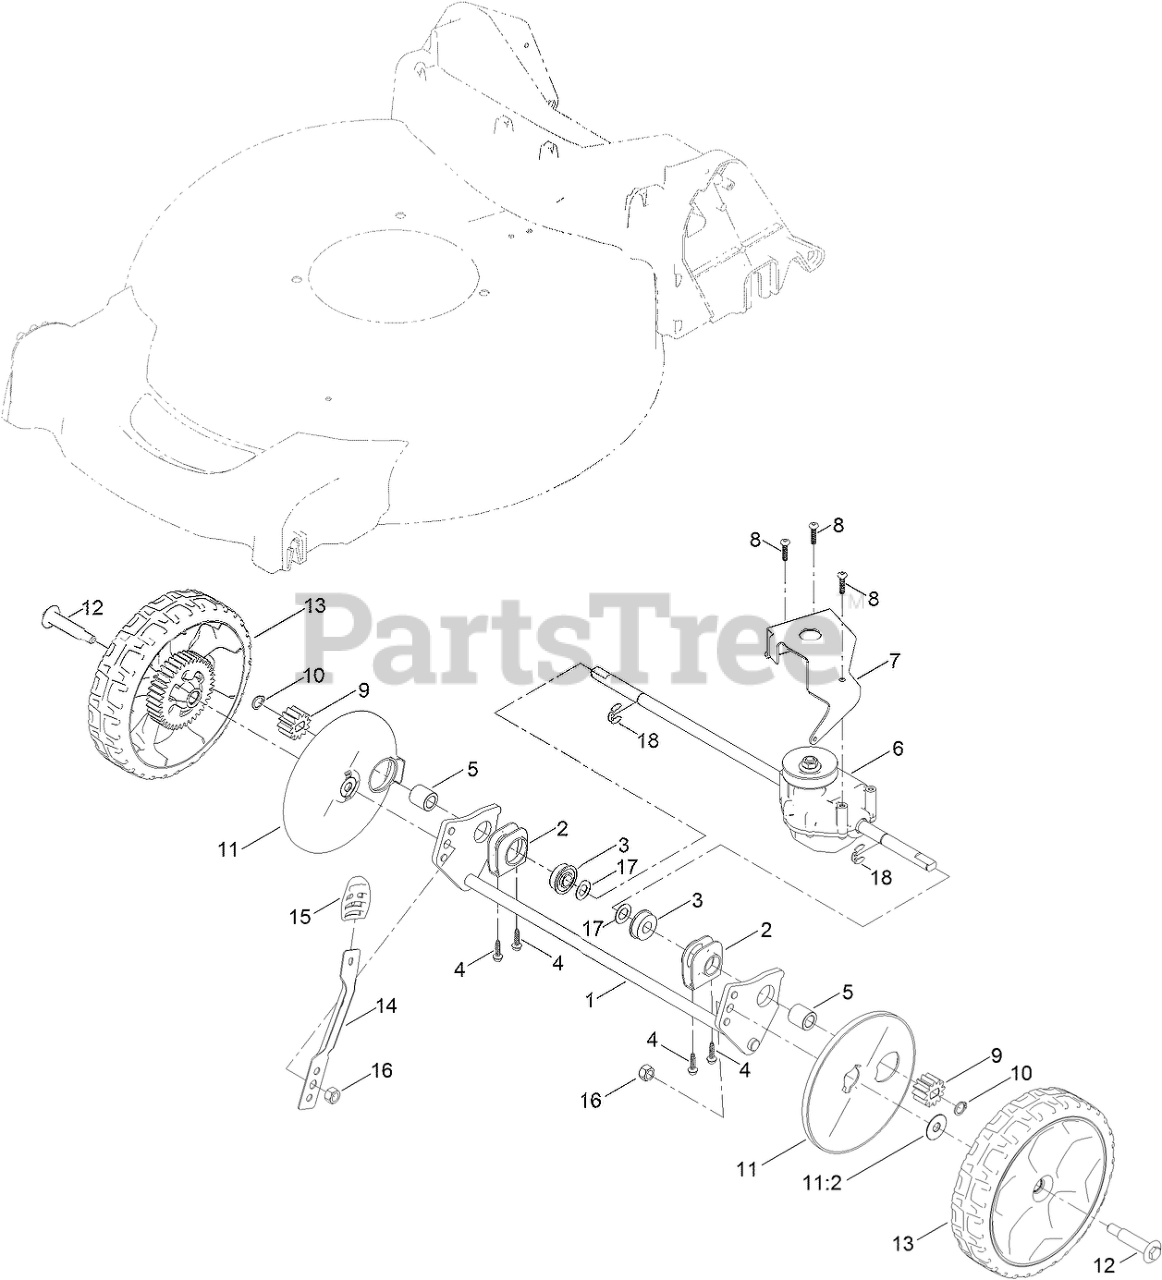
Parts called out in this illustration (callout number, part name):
1	AXLE-REAR
2	RETAINER-BEARING
3	BEARING-BALL
4	SCREW-PLASTIC, HWH
5	BUSHING-SLEEVE
6	TRANSMISSION
7	BRACKET-TRANSMISSION
8	SCREW-PLASTITE
9	GEAR-PINION
10	RING-RETAINING
11	WHEEL COVER ASM
11:2	WASHER-STEPPED
12	BOLT-SHOULDER
13	8 INCH WHEEL GEAR ASM
14	ARM-SPRING
15	KNOB-LEVER, HOC
16	LOCKNUT
17	WASHER-PLAIN
18	RING-RETAINING,CLIP
